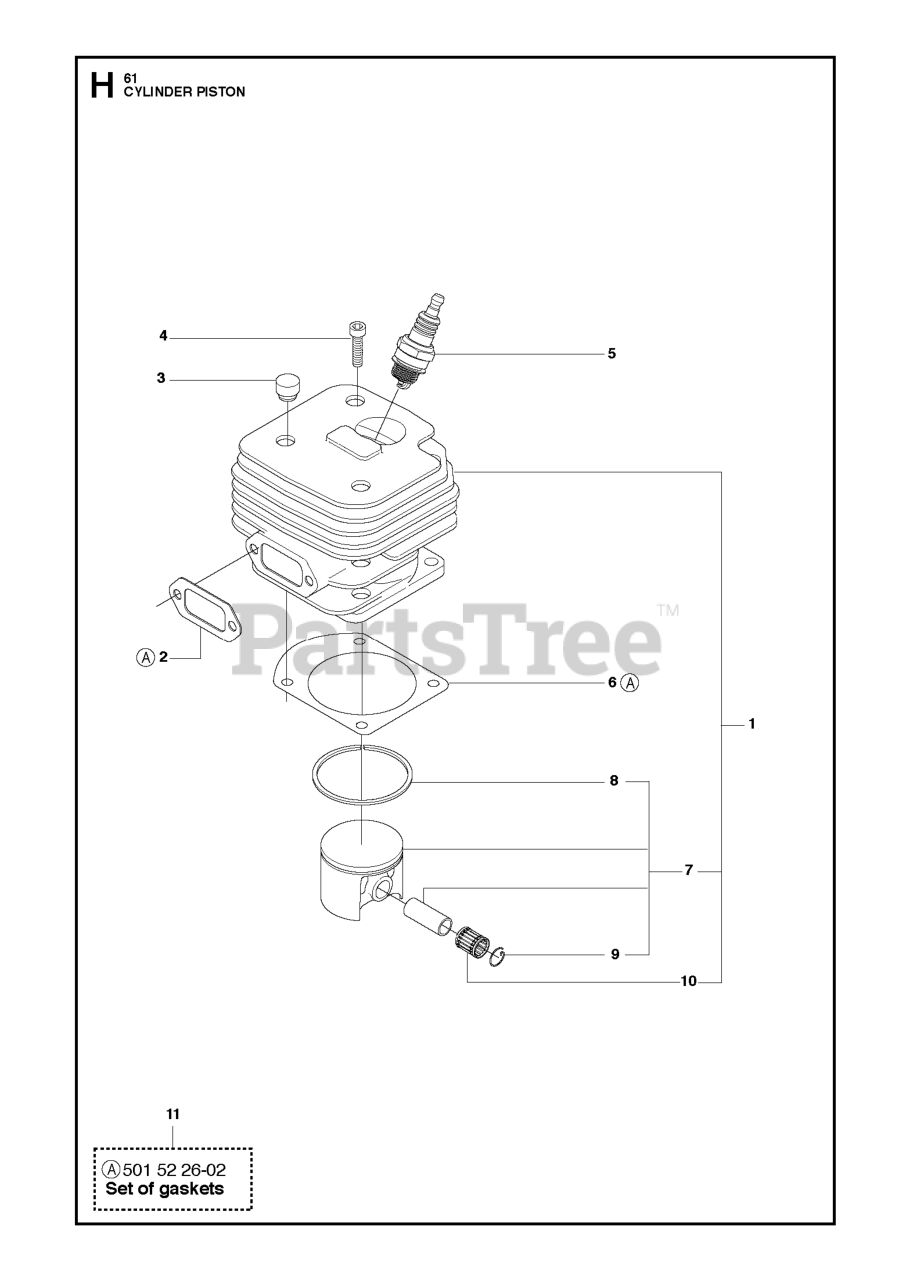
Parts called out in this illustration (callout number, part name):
1	CYLINDER ASSY
3	RUBBER BUMPER
5	SPARK PLUG M14X1.25 NGK BPMR7A
7	PISTON ASSY
8	PISTON RING
8	PISTON RING DIA 48 MM
9	WRIST PIN CLIP
10	NEEDLE BEARING PISTON PIN 12X1
11	GASKET SET NLA
